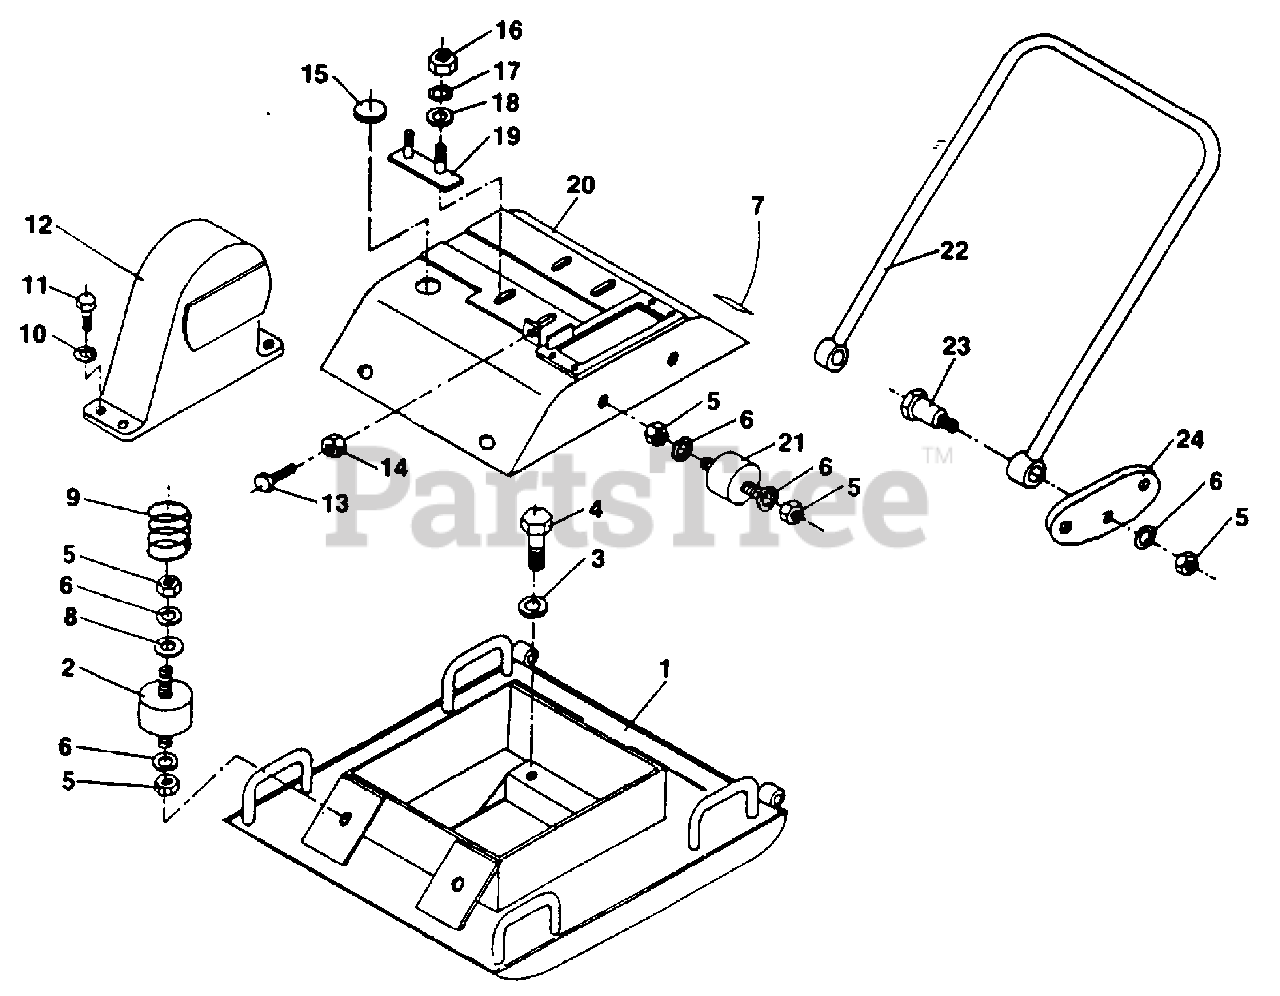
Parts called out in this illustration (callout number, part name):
1	PLATE- Vibration
2	ABSORBER- Shock
3	WASHER- Spring (m18)
4	BOLT- Hex (m18 x 65)
5	NUT- Hex (m12)
6	WASHER- Spring (m12)
7	DECAL- Caution
8	WASHER- Plate (m12)
9	SPRING- Earth
10	WASHER-Spring (m10)
11	BOLT- Hex (m10 x 25)
12	COVER- Belt
13	BOLT- Hex (m10 x 45)
14	NUT- Hex (m10)
16	NUT- Hex (m8)
17	WASHER- Spring (m8)
18	WASHER- Plate (m8)
19	SEAT- Engine
20	COVER- Vibration Plate
21	ABSORBER- Shock
23	PIN- Bracket
24	BRACKET- Handle
